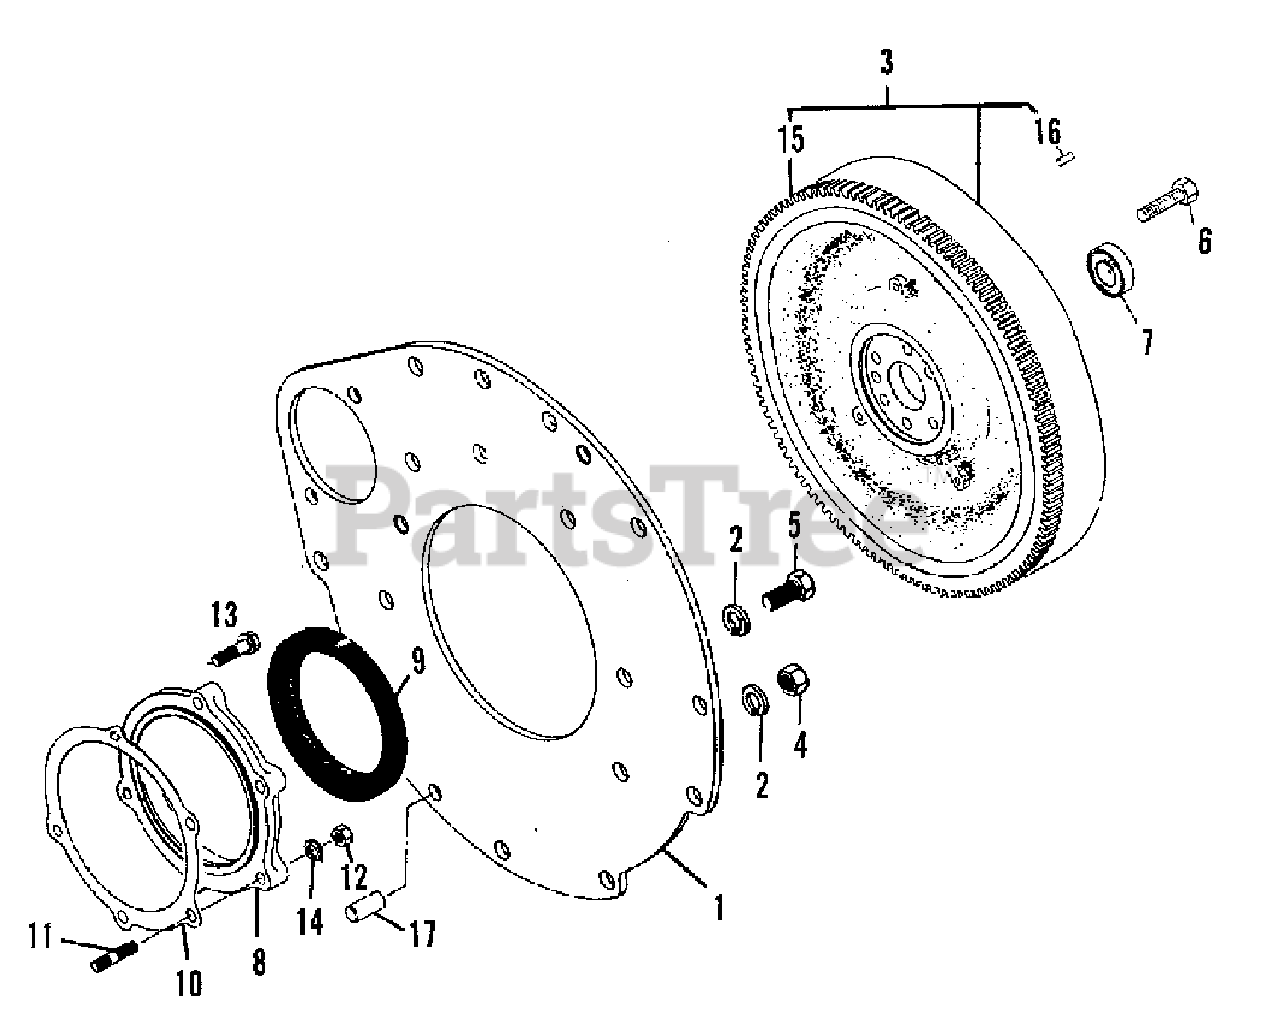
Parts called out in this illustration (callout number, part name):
1	PLATE, rear
2	LOCKWASHER M12
3	FLYWHEEL ASSEMBLY (Incl. Items 15, 16)
5	CAPSCREW, M12 x 25
6	BOLT M10 x 34
7	BEARING, ball
8	COVER ASSEMBLY, oil, rear
9	SEAL, oil, rear
11	STUD, M8 x 36
13	CAPSCREW, m12 x 30
14	LOCKWASHER, M8
15	GEAR, ring
16	PIN, dowel
